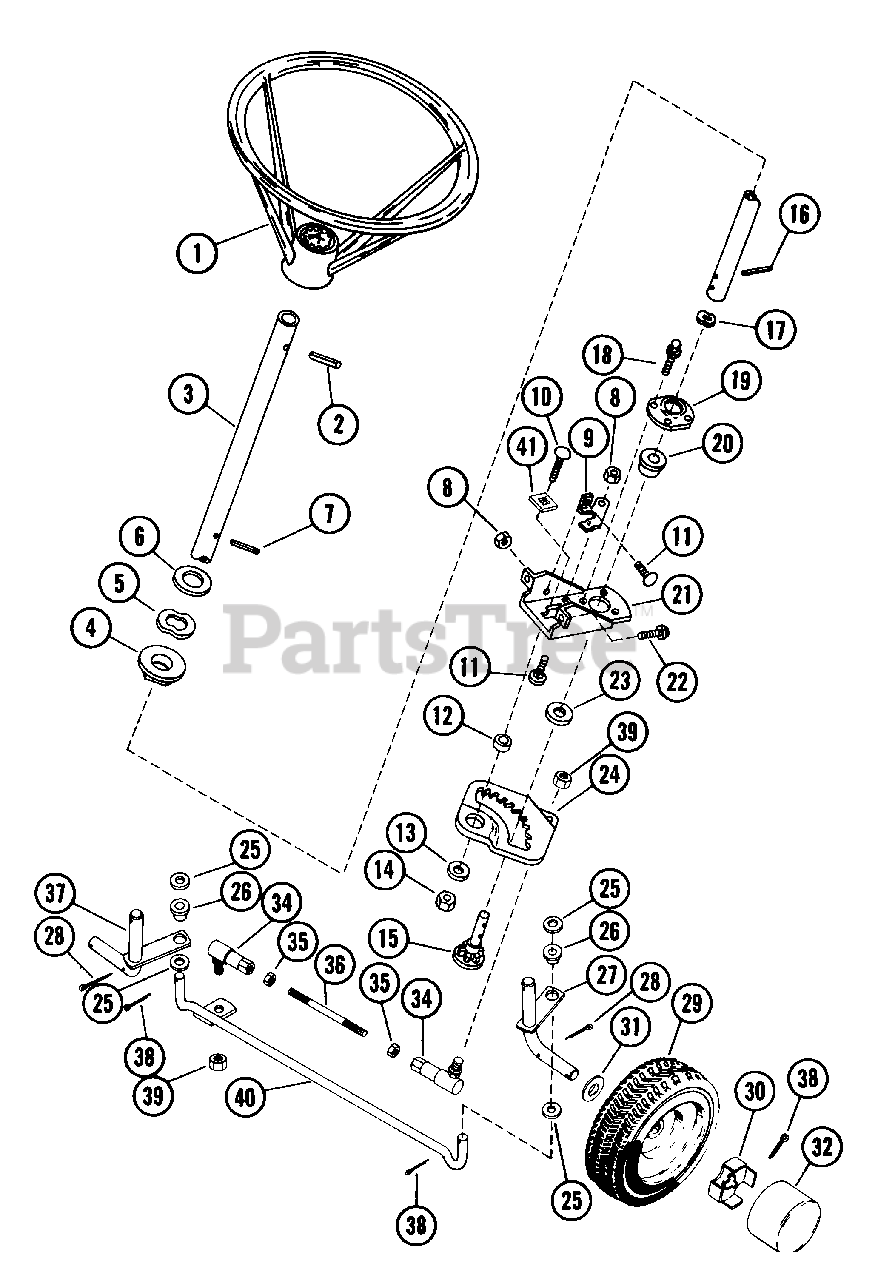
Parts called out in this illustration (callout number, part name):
1	STEERING WHEEL
2	PIN-ROLL .250X1.75
3	STEERING SHAFT
4	FLANGE BUSHING
5	Wave Washer
6	WSHR-FL-STL .755X1.375X.062 PL
7	PIN-ROLL .188X1.25
8	NUT-LK-CTR .250-20 PL
9	ADJUSTMENT BRACKET
10	BLT-RDHDSQSHNK .38-16X1.00 PL
11	BLT-RDHDSQNK .25-20X.62 PL
12	SPACER .380X.750X.236
13	WSHR-FL-STL .390X1.500X.125
14	NUT-LK-CTR .375-16 GR A PL
15	PINION
16	PIN-ROLL .188X1.00
17	Wave Washer
18	SCR-TAP 10-24X.25 CRSLPH PL 1A
19	RETAINING PLATE
20	BSHG-FLG .625X1.156X.375 SI
21	STEERING BRACKET
22	BLT-SERHFWH .31-18X.50 PL
23	WSHR-FL-STL .630X1.005X.062 PL
24	STEERING GEAR
25	WSHR-FL-STL .505X.875X.024 PL
26	BSHG-FLG.500X.625X.312X.750NY
27	L H WHEEL SPINDLE
28	PIN-COTR .12 X 1.25 PL
29	FRONT WHEEL ASSEMBLY
29	TIRE 4.10/3.50-4
29	WHL
29	ZERK FITTING
29	BSHG-FLG .750X1.380X.750X1.557
29	BRG-BALL .752X1.50X.50
30	Spindle Cup
31	SPINDLE WASHER
32	Hub Cap
34	Ball Joint
35	NUT .375-24 PL
36	STEERING LINK
37	R H WHEEL SPINDLE
38	PIN-COTR .12X1.0 PL
39	NUT-LK .375-24 PL
40	TIE ROD
41	WASHER
